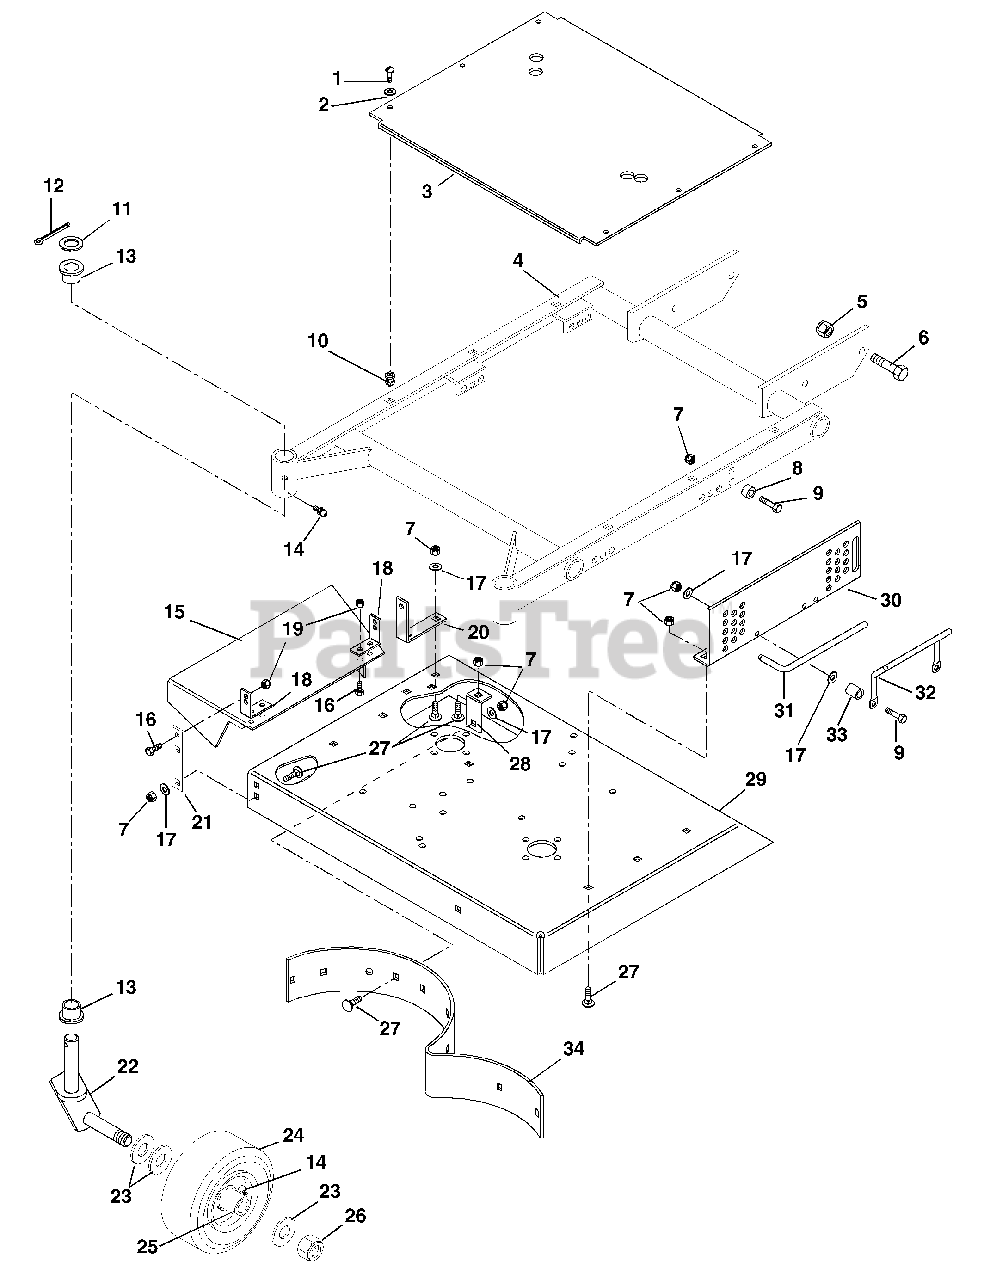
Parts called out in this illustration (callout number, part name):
1	Screw-Self Tapping .25-20 x .50
2	Washer, Flat Steel .281 x .62 x .065
3	Cover, Belt
4	Weldment, Mower Frame Multi-Mode
5	Nut, Locking Center .62-11
6	Bolt-Hex .62-11 x 1.50 Grade 5
7	Nut, Locking Center .38-16
8	Bushing .391 x .626 x .670
9	Bolt-Hex .38-16 x 1.50 Grade 5
10	Grommet, Plastic
11	Washer-Hardened-Thrust 1.002 x 1.552 x .030
12	Pin-Cotter .18 x 1.50
13	Bushing-Flanged .020 x 1.385 x 1.75
14	Fitting-Lube .25-28 x .256
15	Chute, Discharge
16	Bolt-Hex .31-18 x .75
17	Washer-Flat-Steel .406 x .812 x .065
19	Nut-Locking Center .31-18
22	Weldment, Caster Fork
23	Washer-Flat-Steel .812 x 1.50 x .135
24	Wheel 9 x 3.50
25	Bearing, 1.00 x 2.046 x .591
26	Nut-Locking Center .75-10
27	Bolt-Round Head Square Neck .38-16 x 1.00 Grade 5
28	Bracket, Mower Support
29	Weldment, 36" R.D. Deck
30	Bracket, Mower Side Support Left Hand
30	Bracket, Mower Side Support Right Hand
31	Pin, Mower Locking
